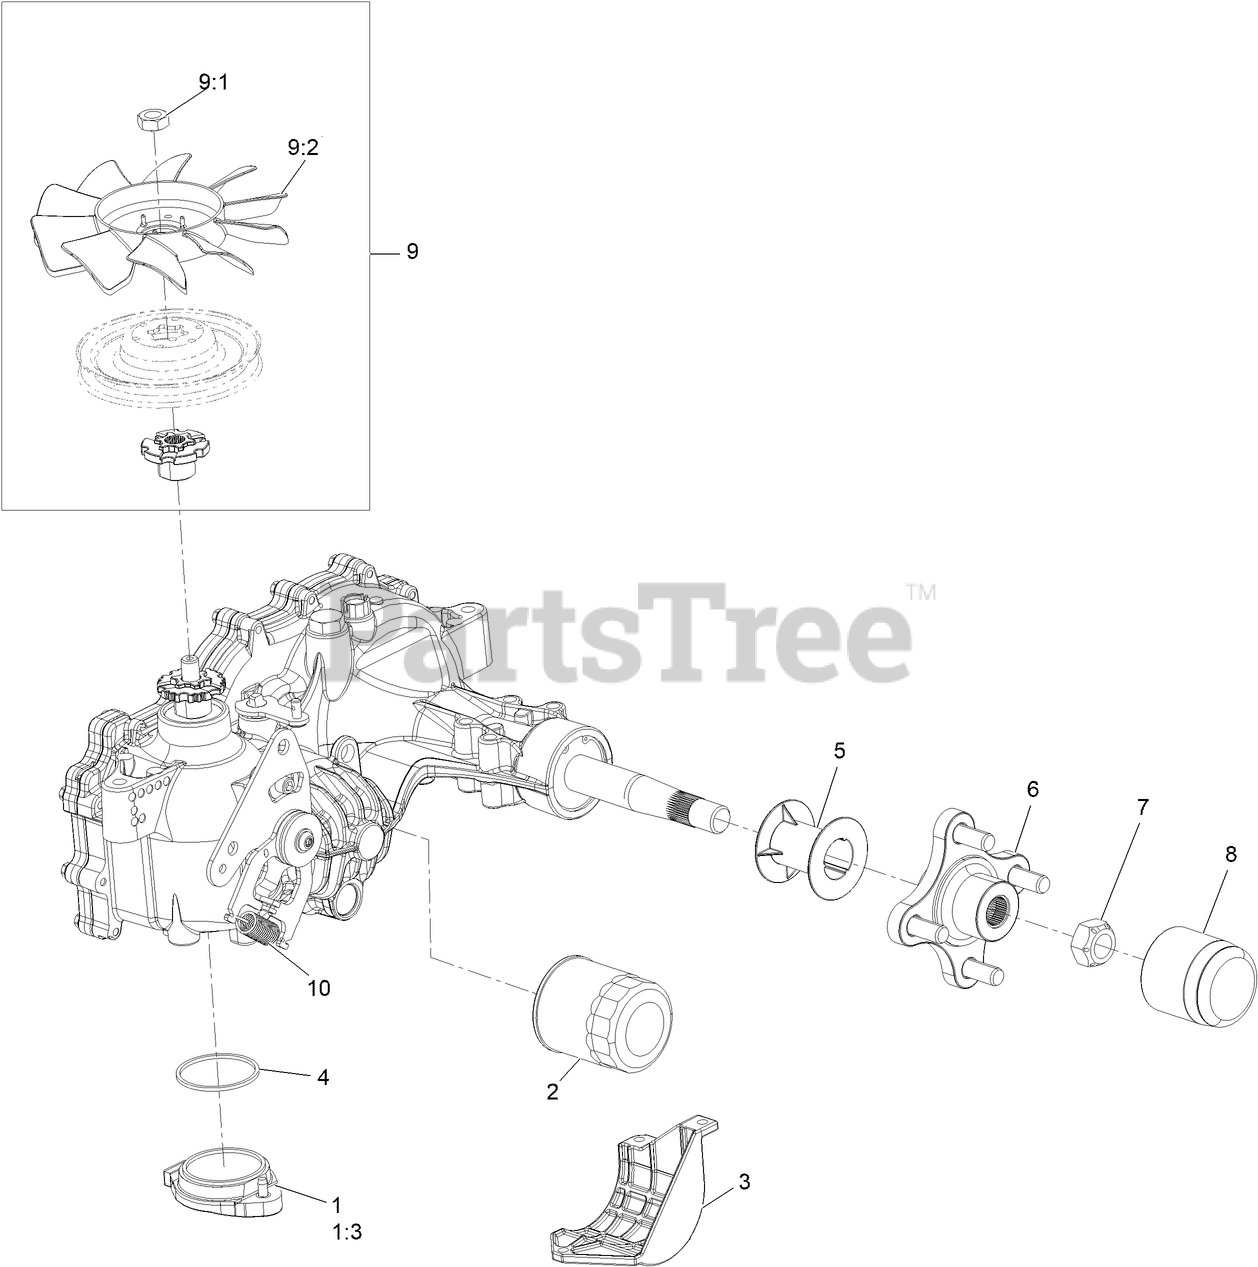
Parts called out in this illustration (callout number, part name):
1	CHARGE KIT
1:3	O RING-SEAL
2	ELEMENT-OIL FILTER, HYD
3	GUARD-FILTER, LH
4	O RING-SEAL
5	TUBE-AXLE
6	HUB-OFFSET
7	NUT-HUB
8	CAP-AXLE, LONG
9	Fan And Pulley Kit
10	SPRING-EXTENSION
